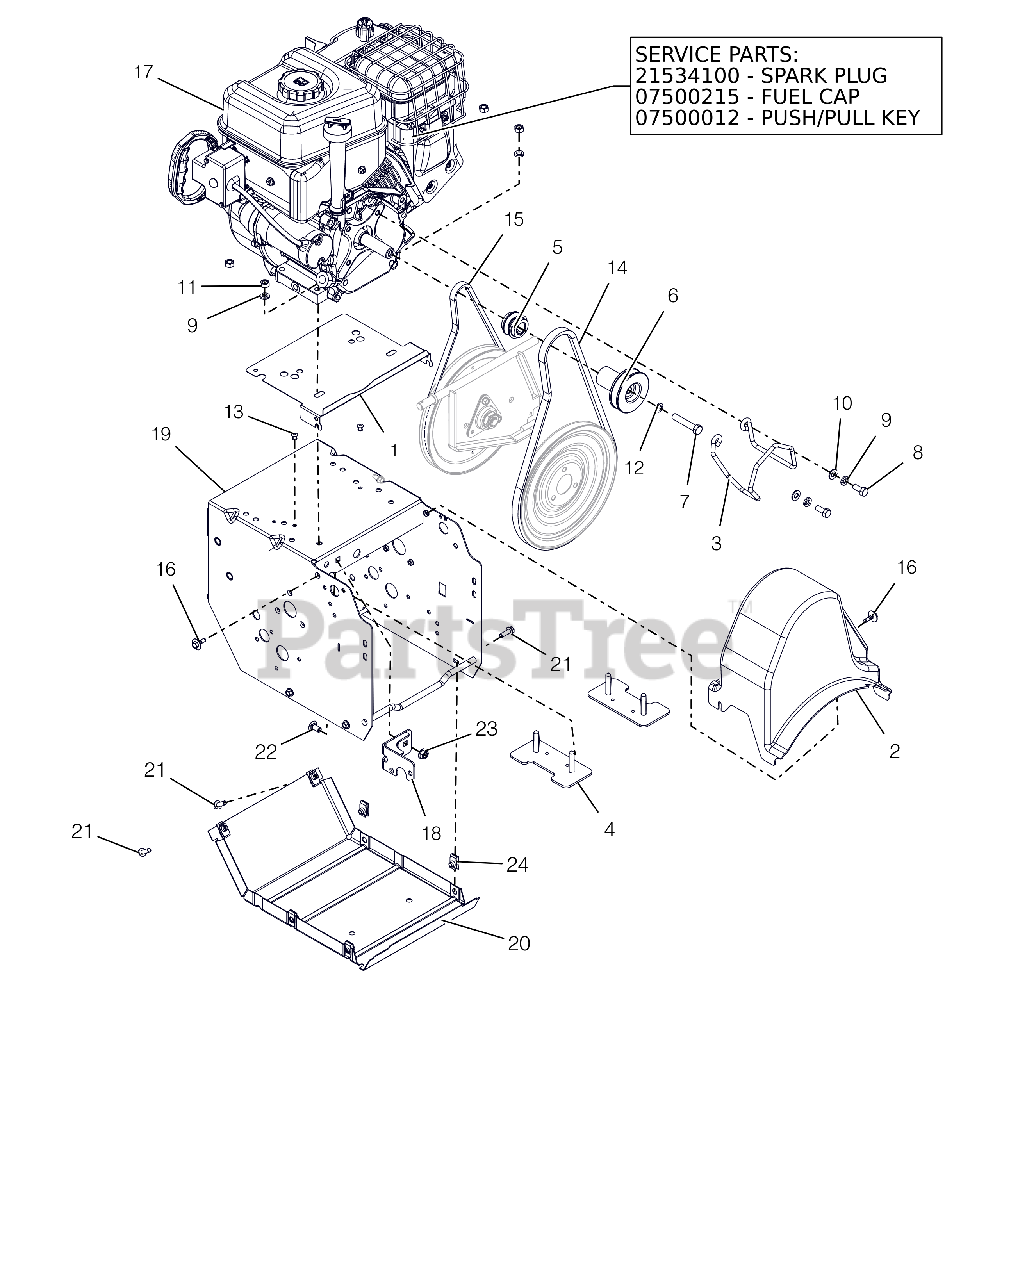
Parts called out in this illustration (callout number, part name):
1	BAFFLE, COMPACT
2	COVER, COMPACT BELT
3	FINGER, BELT
4	STRAP, ENGINE BOLT-WELDMENT
5	TRACTION SHEAVE HALF
6	SHEAVE, AUGER 3/4 - PM
7	BLT-HEX .38-24X2.0 YWZC
8	BLT-HEX .31-24X.75 YWZC GR5
9	WSHR-LK .312X.097 HVY YWZC
10	@WSHR-FL-STL.344X.688X.065YWZC
11	@NUT-HEX .31-18 YWZC
12	WSHR-LK .312X.097 HVY YWZC
13	RVT-POP .187 YZ
14	V-BELT, HA-RAW EDGE
15	V-BELT, 3L-WRAPPED
16	SCR-TAP .25-20X.5 CAPTIVE
17	ENGINE, BRIGGS 900, RECOIL 60W
17	PLUG, SPARK
17	CAP, FUEL - BRIGGS & STRATTON
17	KEY, IGNITION PUSH/PULL B&S
18	WELDMENT, FRAME BRACKET
19	FRAME, MAIN
20	COVER, BOTTOM
21	BLT-HEX .25-20X.75 HWH YZ GR5
22	@BLT-RHDSSQNK .31-18X.62 G5YZ
23	@NUT-LK-TOP-FLG .31-18 YWZC
24	NUT-RTNR .25-20X.56
